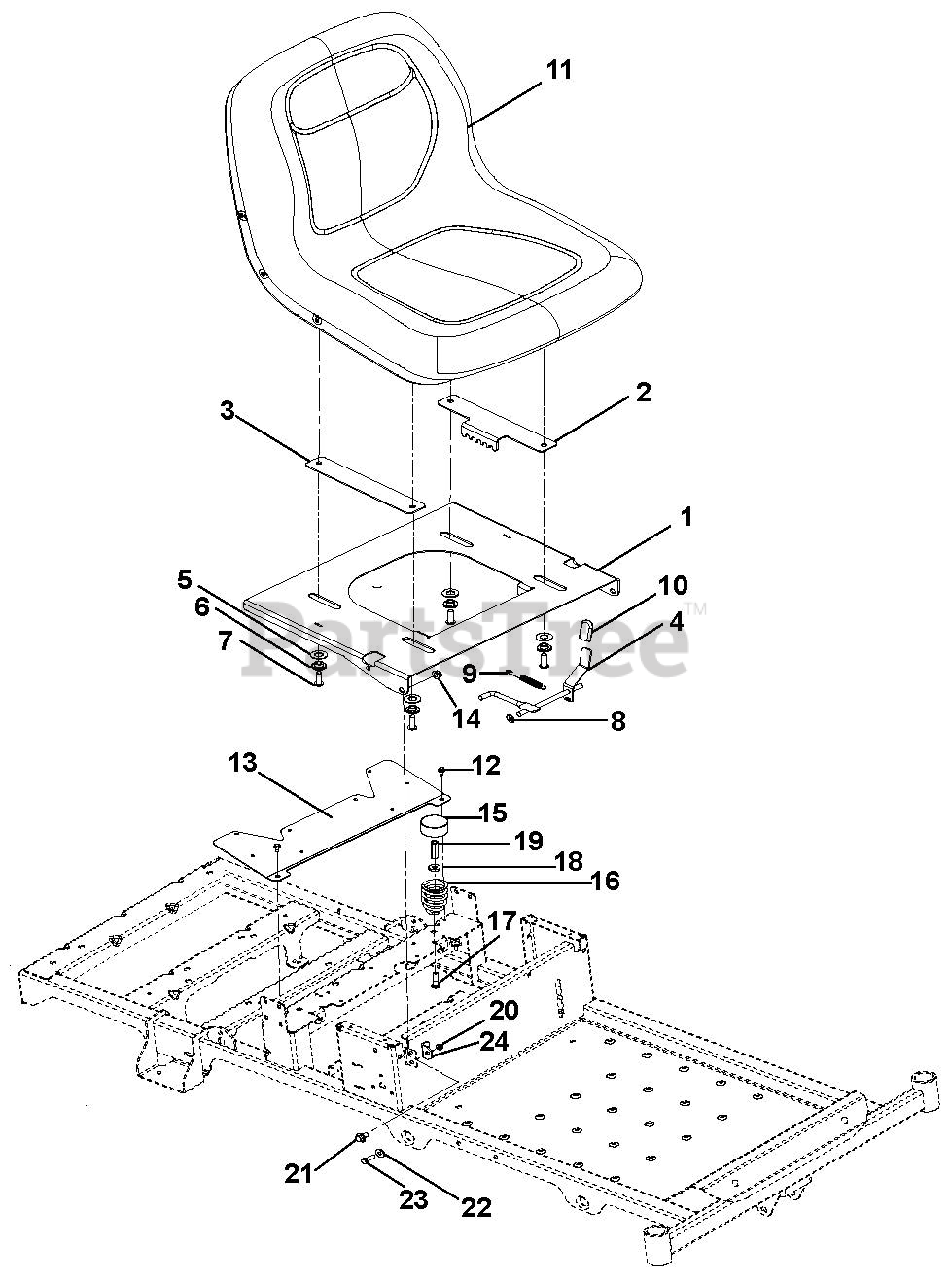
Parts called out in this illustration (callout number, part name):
1	Plate, Adjustable Seat
2	Plate, Adjustable Seat Track
3	Plate Adjustable Seat Slide
4	Weldment, Adjustable Seat Latch
5	Washer, Flat Steel .505 x 1.00 x .062
6	Bushing, Flange .32 x .500 x .344 x .880
7	Screw, Socket Head, Button Head .31-18 x 1.00
8	Push Nut 5/16
9	Spring Tension .043 x .44 x 3.31 Weldment 5.8
10	Grip, Seat Lever, Grey
11	Seat, Milsco XB180 Grey
12	Screw, Tapping .25-20 x .50 Hex Washer Head Thread
13	Guard, Fan
14	Nut, .38-16 Locking Top Flange
16	Spring, Seat
17	Bolt, Round Head Square Neck .31-18 x 1.50
18	Washer, Flat Steel .328 x .87 x .179
19	Nut, Coupling 5/16-18 x 1.75
20	Nut, 5/16-18 Flange Nyloc
21	Bolt, Shoulder .375-16 x .135
22	Bushing, Flange .325 x .499 x .26 x .88
23	Bolt, Hex .31-18 x 1.00
24	Bracket, Seat Stop
